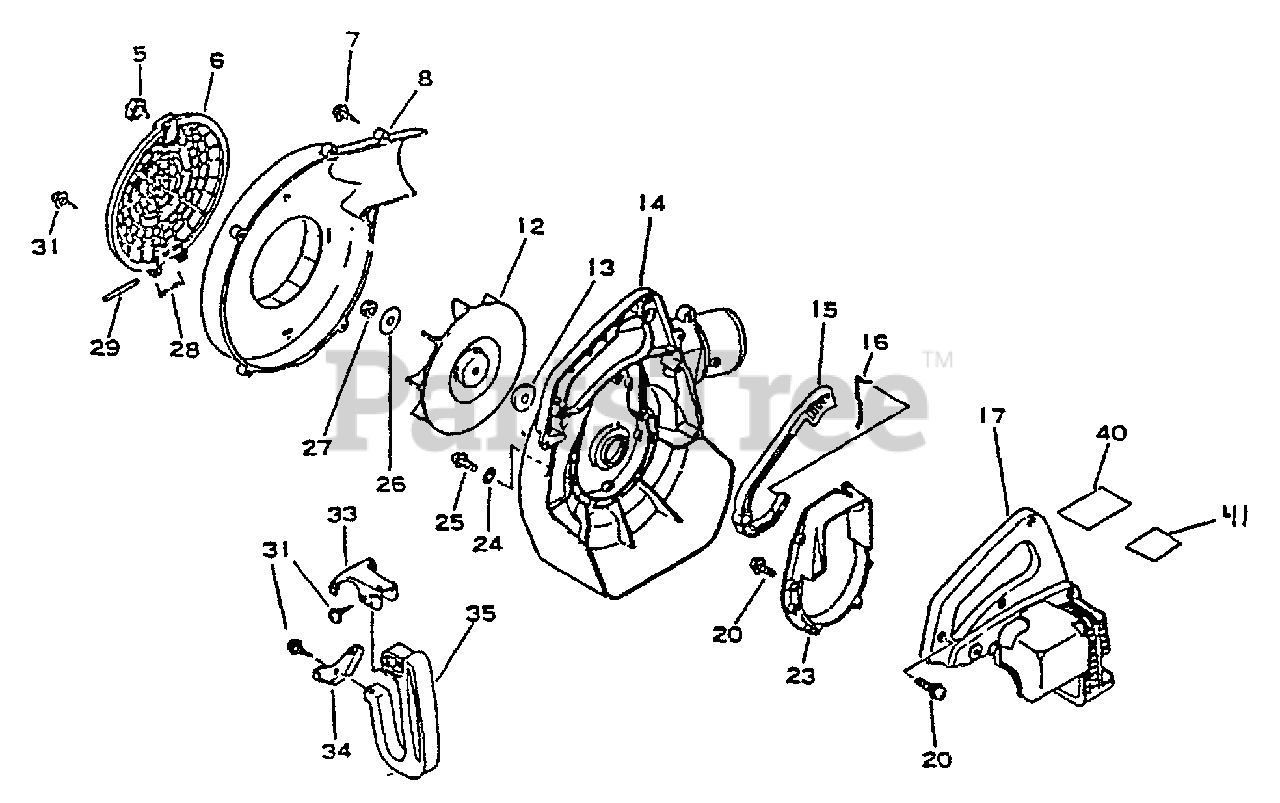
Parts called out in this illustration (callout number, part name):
5	THUMBSCREW
6	SHIELD, DEBRIS
7	SCREW 5×20
8	COVER, FAN - LEFT
12	FAN
14	COVER, FAN - RIGHT
15	TRIGGER, THROTTLE
16	ROD, THROTTLE
17	COVER, ENGINE
20	SCREW 4×18
23	BRACKET, ENGINE
25	SCREW 4×22
26	WASHER
28	SPRING, COIL
29	PIN, INTAKE COVER
31	SCREW 5×20
33	BRACKET, UPPER HANDLE
34	BRACKET, LOWER HANDLE
40	LABEL, MODEL
41	LABEL, CAUTION
